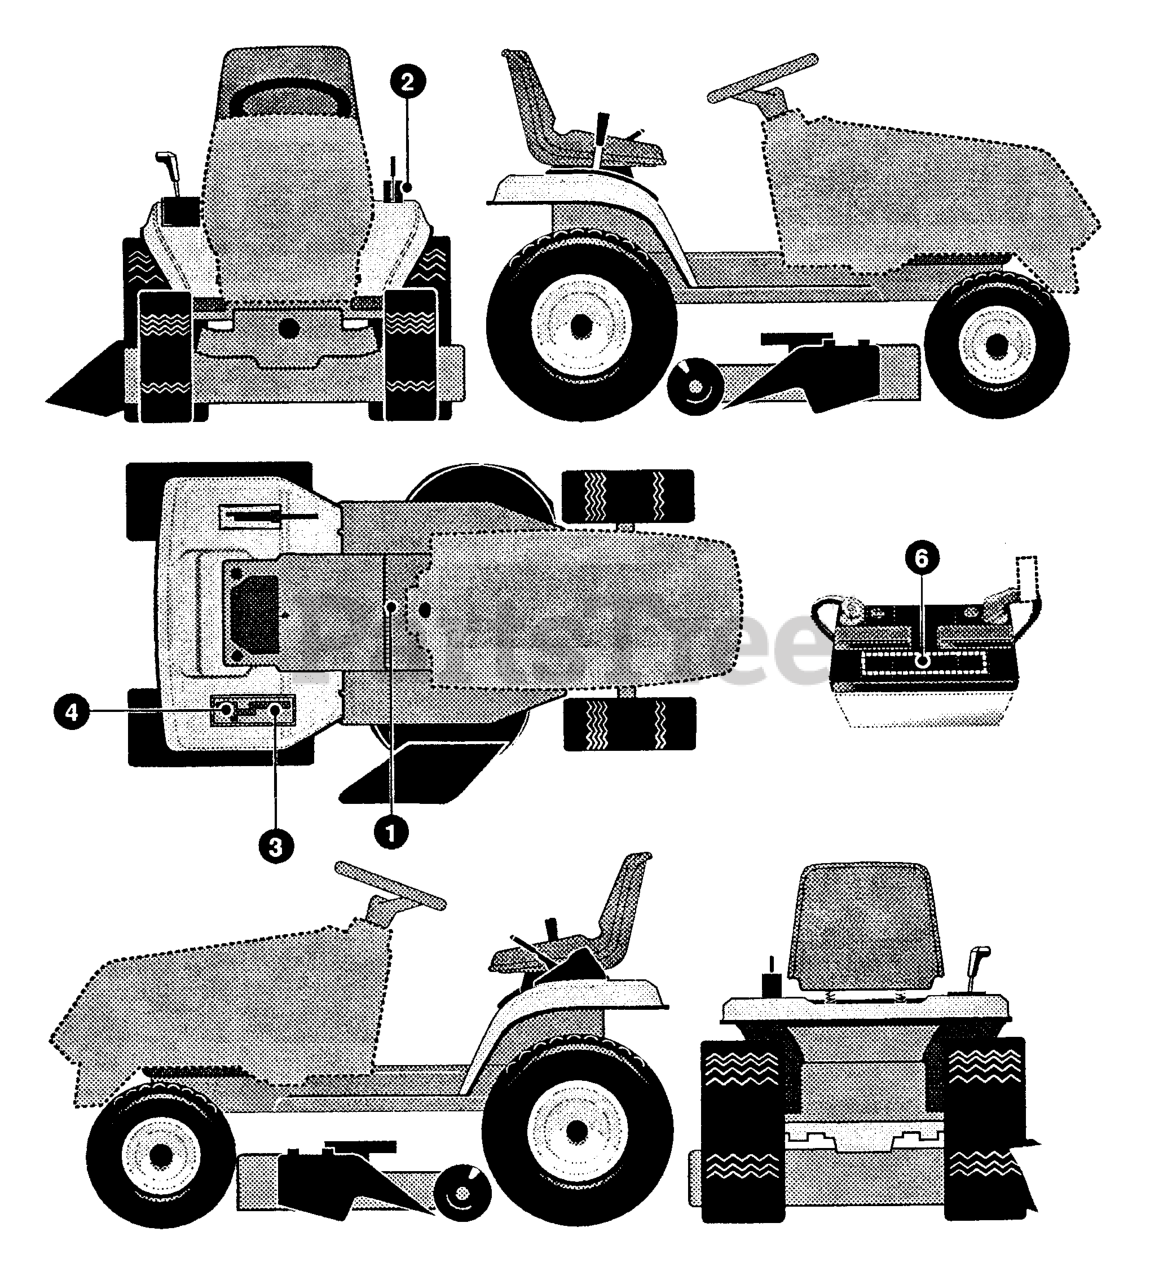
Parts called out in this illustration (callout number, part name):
1	CAUTION CONSOLE TOP
2	HEIGHT ADJUST
3	SHIFTER POSITION
4	SHIFT REV/NEUTRAL
6	BATTERY FRE/ENG
